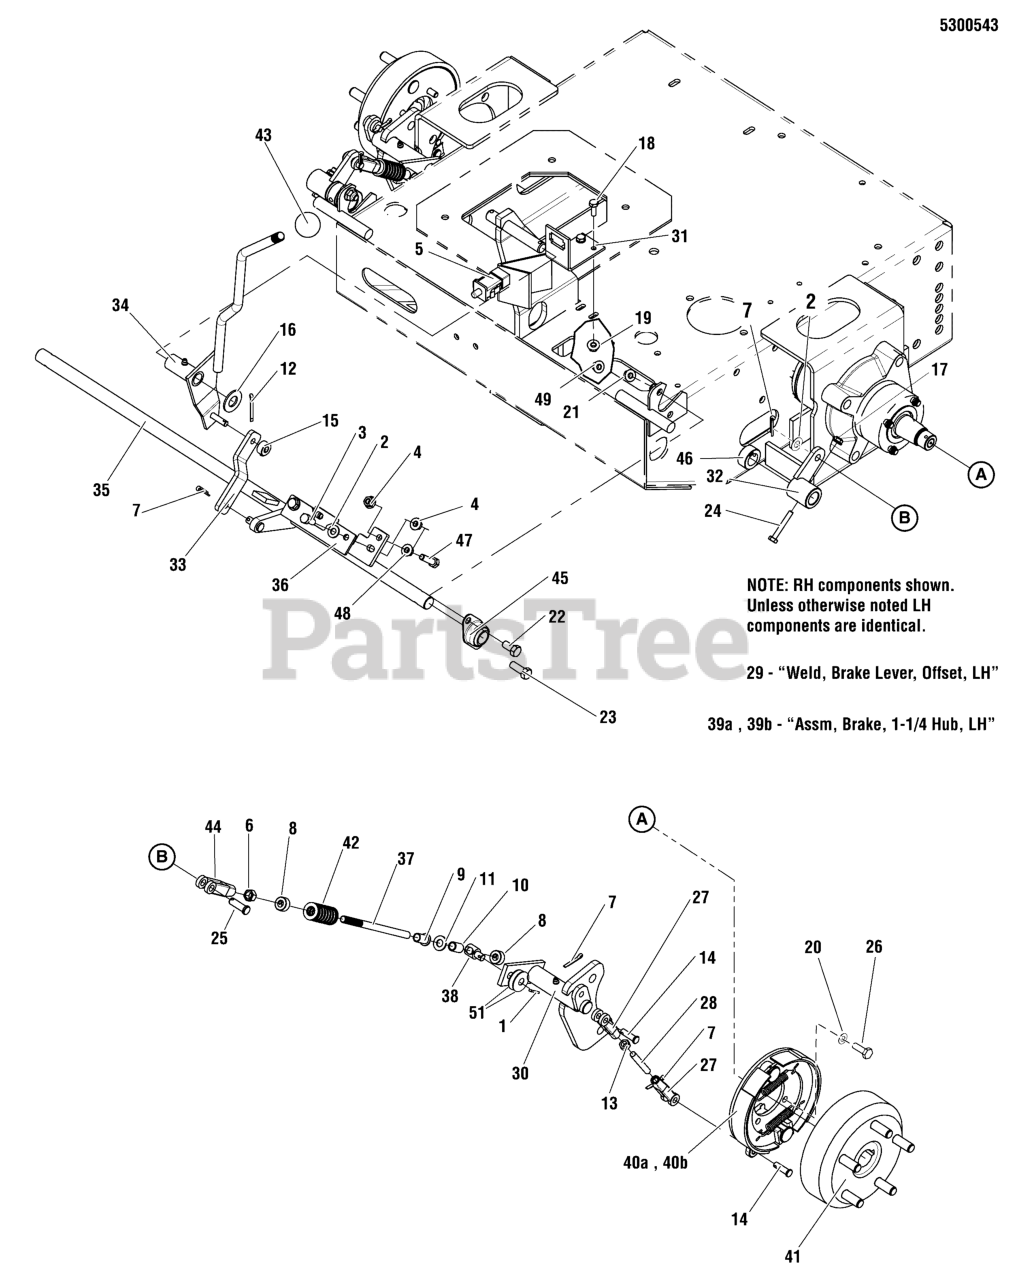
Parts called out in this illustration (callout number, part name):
1	PIN, 3/32 X 0.750, COT, ZINC/CLEAR
2	WASHER, 5/16" SAE
3	BOLT, 5/16-18 X 3/4 GD5
4	NUT, 5/16-18 HEX SERRATED FLANGE (SMALL)
5	SWITCH, DP NO/NC SNAP-IN
6	NUT, 3/8-24 HEX
7	PIN, COTTER, 1/8" X 3/4
8	COLLAR, 3/8" SET
9	BUSHING, NYLON
10	SPACER, .38 X .50 X .27
11	WASHER, 3/8 SAE
12	PIN, COTTER, 1/8 X 1-1/4
13	NUT, 5/16-24 HEX
14	PIN, CLEVIS, 5/16" X 1
15	COLLAR, 5/16" SET
16	WASHER, 5/8" SAE
17	NUT, 1/4-20 HEX NYLOCK FLANGE
18	BOLT, 1/4-20 X 3/4" GD5 YZ
19	NUT, 1/4-20 HEX SERR. FLANGE
20	WASHER, 5/16 LOCK CZ
21	NUT, 3/8-16 HEX NYLOCK FLANGE
22	BOLT, 3/8-16 X 3/4" GD5 CZ
23	BOLT, 3/8-16 X 1" GD5 CZ
24	BOLT, 1/4-20 X 1-3/4" GD5 YZ
25	PIN, CLEVIS, 3/8" X 1-1/8"
26	BOLT, 5/16-18 X 3/4 12PT FLANGE - PATCH
27	CLEVIS, 5/16-24, STEEL, CLEAR ZINC
28	LINK, STUD
29	WELD, BRAKE LEVER OFFSET - LH - RED
30	WELD, BRAKE LEVER OFFSET - RH - RED
31	BRACKET, SWITCH MOUNT - RED
32	WELD, PIVOT LINKAGE MOUNT - RED
33	LINK
34	BRAKE LEVER WELDMENT
35	WELD, PARKING BRAKE SHAFT - RED
36	PLATE, NEUTRAL LOCK - RED
37	ROD, BRAKE ADJUSTMENT
38	ADJUSTER, BRAKE LINKAGE
41	BRAKE DRUM, 6", 5 BOLT, KNOTT
42	SPRING, COMPRESSION 2" MEDIUM
43	KNOB, PLASTIC, 1/2-13
44	CLEVIS, 3/8-24 RH
45	BEARING, BRONZE FLANGE, 3/4
46	COLLAR, 3/4" SET
47	BOLT, 5/16-18 X 1-1/4" GD5
48	NUT, 5/16-18 HEX JAM
49	NUT, 3/8-16 HEX NYLON LOCK
51	WASHER, .389 X 1.00 X .020, SS
